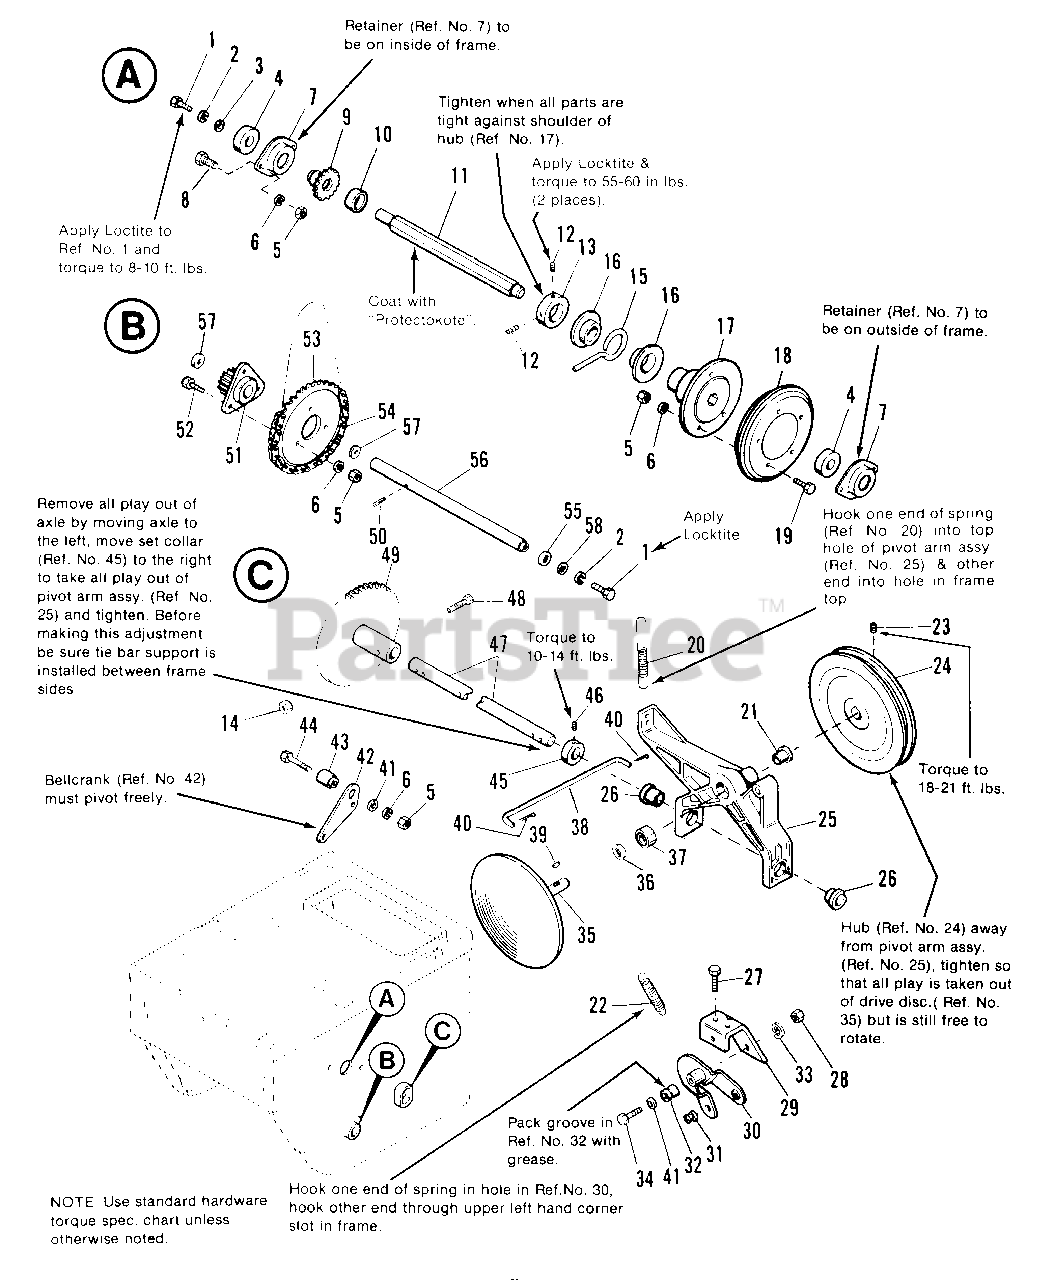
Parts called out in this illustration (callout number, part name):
1	CAPSCREW, Hex Hd., 1/4-20 x 5/8
2	LOCKWASHER, 1/4
3	WASHER, Flat, 1/4
5	NUT, Hex, 5/16-18
6	LOCKWASHER, 5/16
7	RETAINER, Bearing
8	CAPSCREW, Hex Hd., 5/16-18 x 5/8
9	SPROCKET, 10 Tooth
12	SETSCREW, Socket Hd., 1/4-20 x 3/8
14	NUT, Hex, Lock, 5/16-18
16	COLLAR, Thrust
17	HUB, Friction Disc
18	DISC, Friction
19	CAPSCREW, Hex Hd., 5/16-18 x 3/4
22	SPRING
23	SETSCREW, Sq. Hd, 5/16-18 x 1/2
24	PULLEY, Traction
25	ARM ASSY., Pivot w/Bushings (Incl. all bushings, Qty 1 of Ref. No. 21, Qty 2 of Ref. No. 26; Qty. 1 of Ref. No. 37)
27	SCREW, Taptite, 5/16-18 x 1/2
28	NUT, Hex, 3/8-16
29	BRACKET, Bushing
30	ARM ASSY, Shift w/Bushings (Includes Ref. No. 31)
31	BUSHING, Ball
32	BUSHING, Spacer
33	LOCKWASHER, 3/8
34	CAPSCREW, Hex Hd, 3/8-16 x 2
35	DISC, Drive
39	KEY, Woodruff, 3/16 x 5/8
40	PIN, Cotter, 1/8 x 3/4
41	WASHER, Flat, 5/16
43	BUSHING, Pivot
44	CAPSCREW, Hex Whizlock 5/16-18 x 2-1/4
45	SET COLLAR
46	SETSCREW, Sq. Hd., 5/16-18 x 1/2
48	CAPSCREW, Hex Hd., 5/16-18 x 1-1/2
50	PIN, Roll, 1/8 x 1
52	CAPSCREW, Hex Hd., 5/16-18 x 1
53	SPROCKET, 36 Tooth
54	CHAIN, Drive
55	WASHER, Int. Lock 1/2
58	WASHER, 1/4
